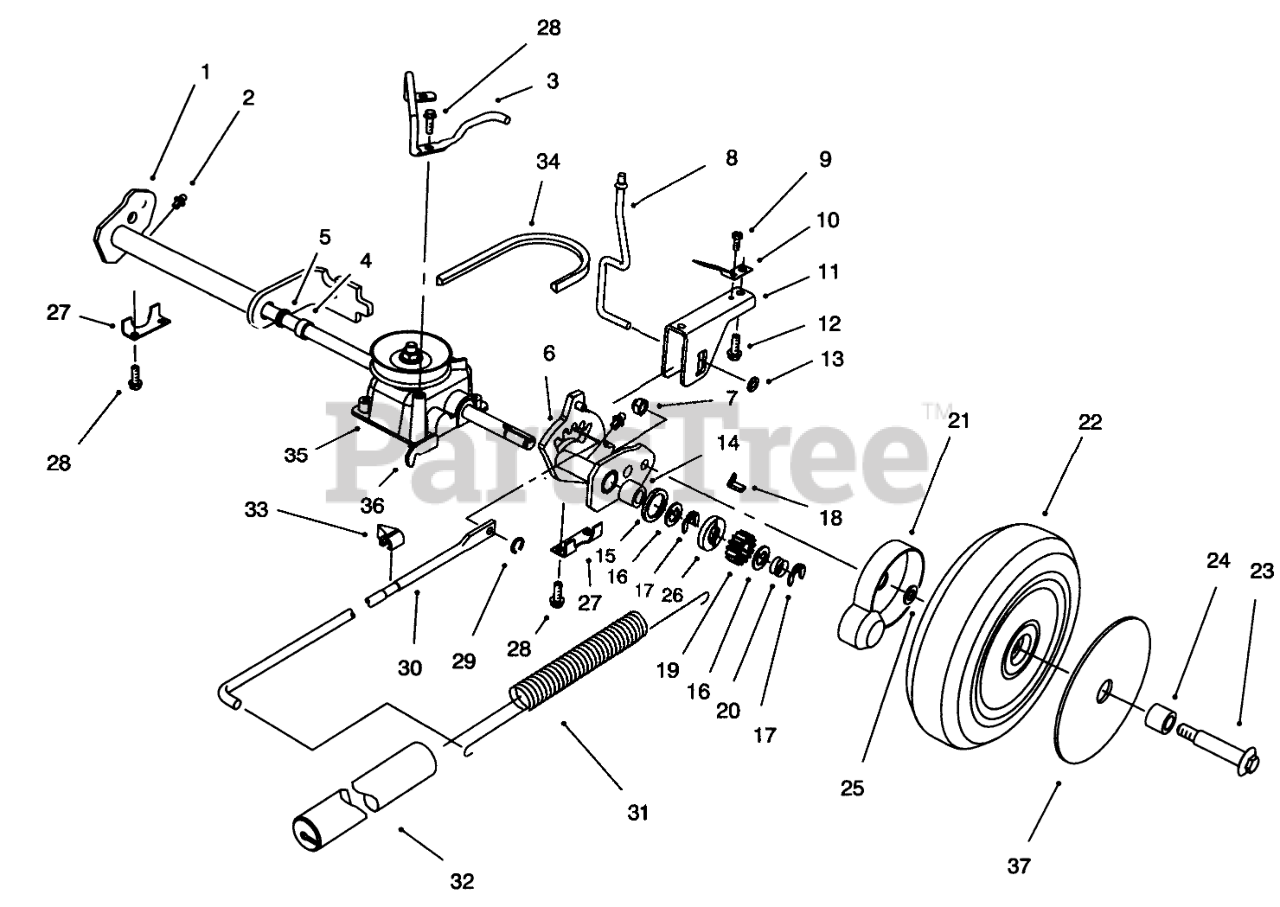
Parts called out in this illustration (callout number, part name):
1	Rear Pivot Assembly R.H. (Incl. Ref. #2, 4, 5 & 14)
2	FITTING-GREASE
3	Retainer Belt
4	BUSHING
5	SEAL-OIL
6	Rear Pivot Assembly L.H. (Incl. Ref. #2, 4, 5 & 14)
7	NUT-HEX
8	TRIGGER ROD
9	SCREW 8 - 32 X 250
10	SPRING - TRIGGER RET
11	SADDLE - HOC
12	SCREW
13	PUSHNUT
14	BEARING-ROLLER
15	RING-FRICTION
16	WASHER-THRUST, KEYED
17	RING-CLIP, LOCKING
18	KEY-ROCKING, LH
19	GEAR-PINION
20	SPRING-COMPRESSION
21	COVER-WHEEL
22	Wheel, Tire & Gear Assy. (Incl. Ref. #24)
23	BOLT-WHEEL
24	BUSHING
25	SPACER-COVER, WHEEL
26	WASHER-CLUTCH
27	REAR SECURING PLATE
28	SCREW-HWH
29	GRIP RING
30	LINK ROD
31	SPRING-COUNTERBALANCE
32	COVER-SPRING
33	INDICATOR-HEIGHT OF CUT
34	V-BELT
35	Gearcase Assembly (Incl. Ref. #36)
36	Bracket-Traction
37	COVER-WHEEL
